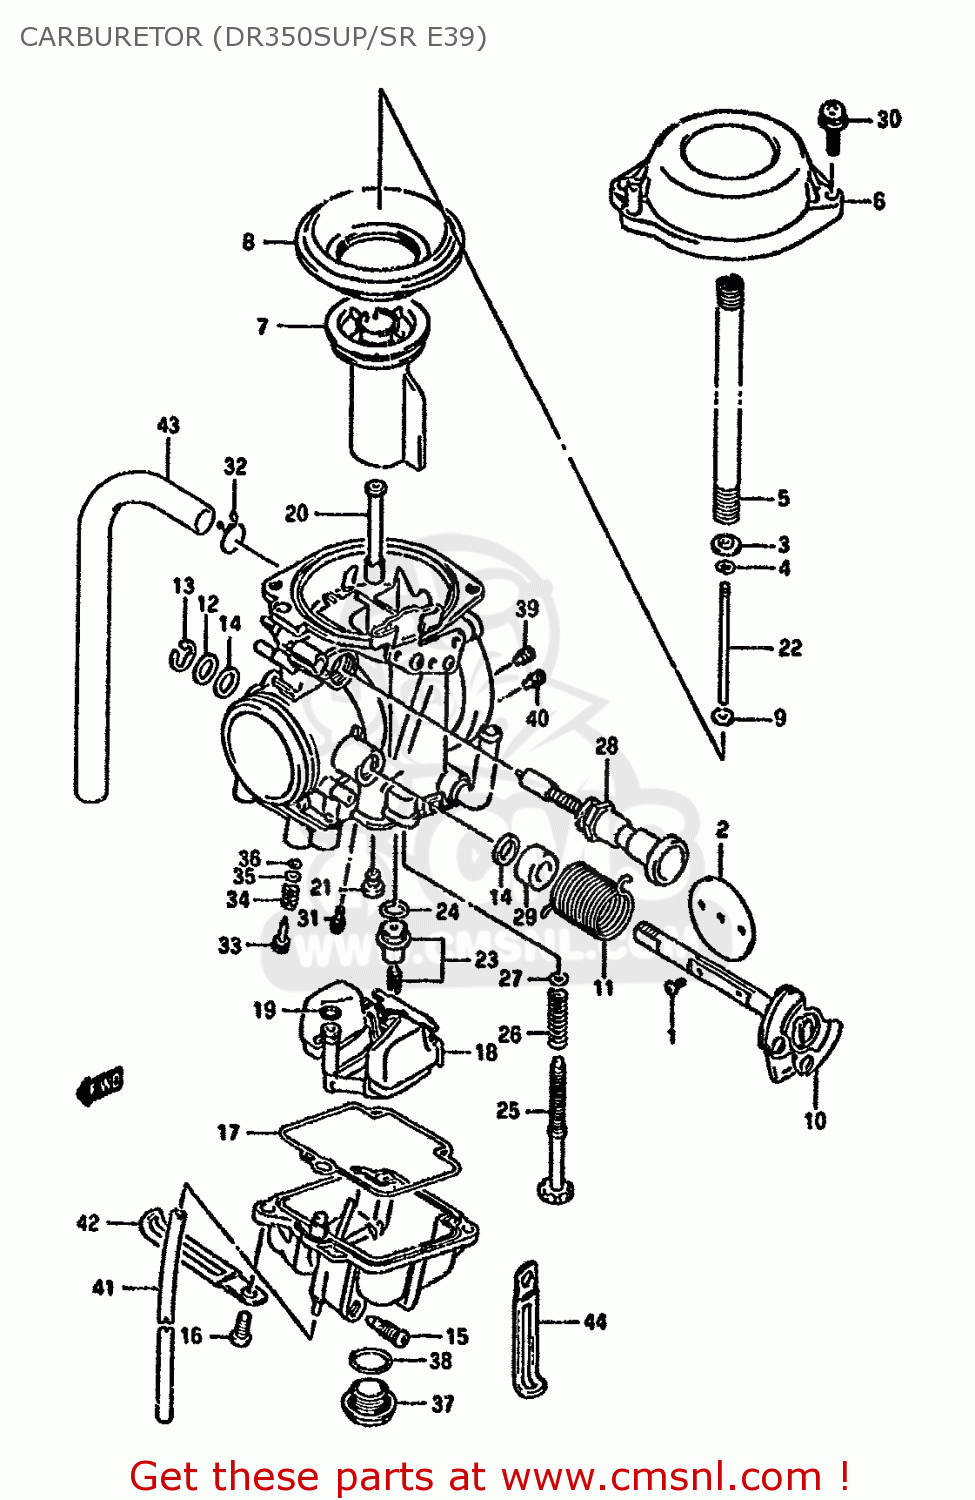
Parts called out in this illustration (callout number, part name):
1	SCREW
2	VALVE,THROTTLE (115)
3	RING
4	E RING
5	SPRING
6	COVER,DIAPHRAGM
7	VALVE PISTON
8	DIAPHRAGM
9	RING
10	SHAFT ASSEMBLY
11	SPRING
12	GASKET,THROTTLE SHAFT (NAS)
13	E RING
14	SEAL
15	SCREW,DRAIN
16	SCREW
17	GASKET,FLOAT CHAMBER (NAS)
18	FLOAT ASSY
19	O RING
20	JET,NEEDLE (O-6)
21	JET,MAIN(130)
22	NEEDLE,JET
23	VALVE ASSEMBLY,NEEDLE
24	O-RING,NEEDLE VALVE
25	SCREW,ADJUSTER
26	SPRING
27	WASHER
28	PLUNGER ASSEMBLY
29	RING
30	SCREW
31	JET,PILOT(37.5)
32	CLIP
33	SCREW,PILOT
34	SPRING
35	WASHER
36	O RING,PILOT AIR SCREW
37	SCREW,GUIDE
38	O RING,DRAIN PLUG
39	JET,AIR(1.2)
40	JET,AIR(0.6)
41	HOSE
42	CLIP
43	HOSE
44	HOSE
45	CLAMP
